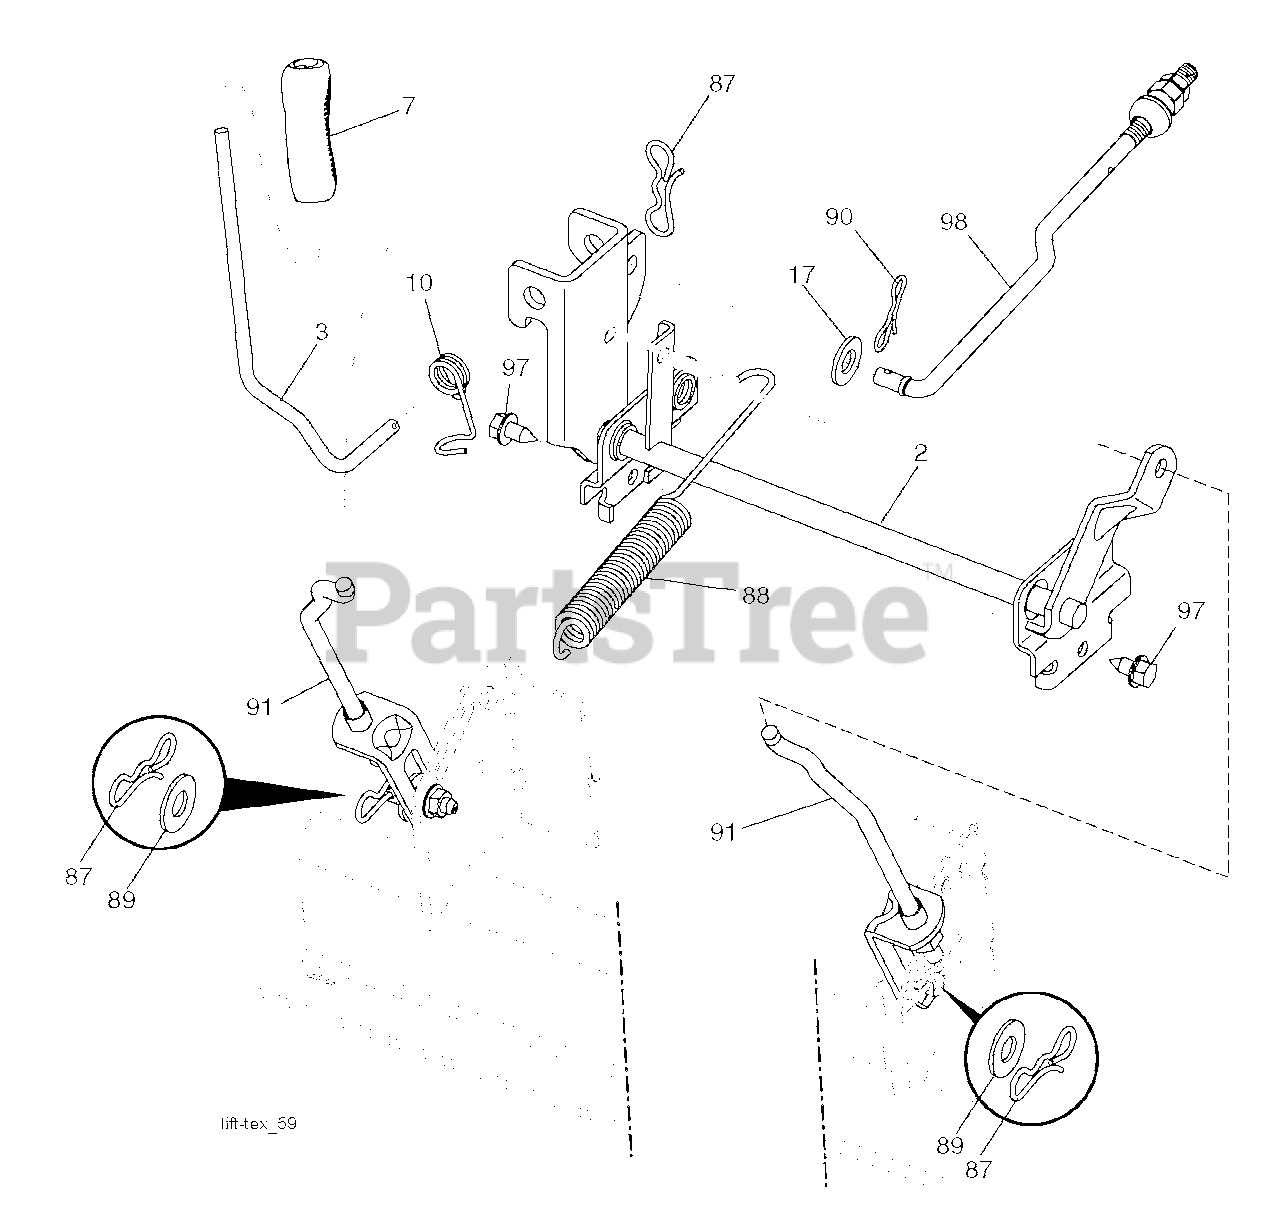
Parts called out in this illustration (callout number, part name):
2	SHAFT.ASM.CROSS.LIFT
3	LEVER.LIFT.HANDLE.LT
7	GRIP.HANDLE.LIFT.PVC.BLACK
10	SPRING.TORSION.LIFT.HANDLE
17	WASHER
87	PIN.COTTER.7/16.BOW TI.
88	SPRING.LIFT.ASSIST
89	WASHER.CLEAR.ZINC
90	PIN.COTTER.5/16.BOW TI
91	LINK.LIFT.ASM.REAR.GT.
97	SCREW, 3/8-16X3/4
98	LINK.FRONT.MOWER.SUSP.ASM.BLK
100	LOCKNUT
